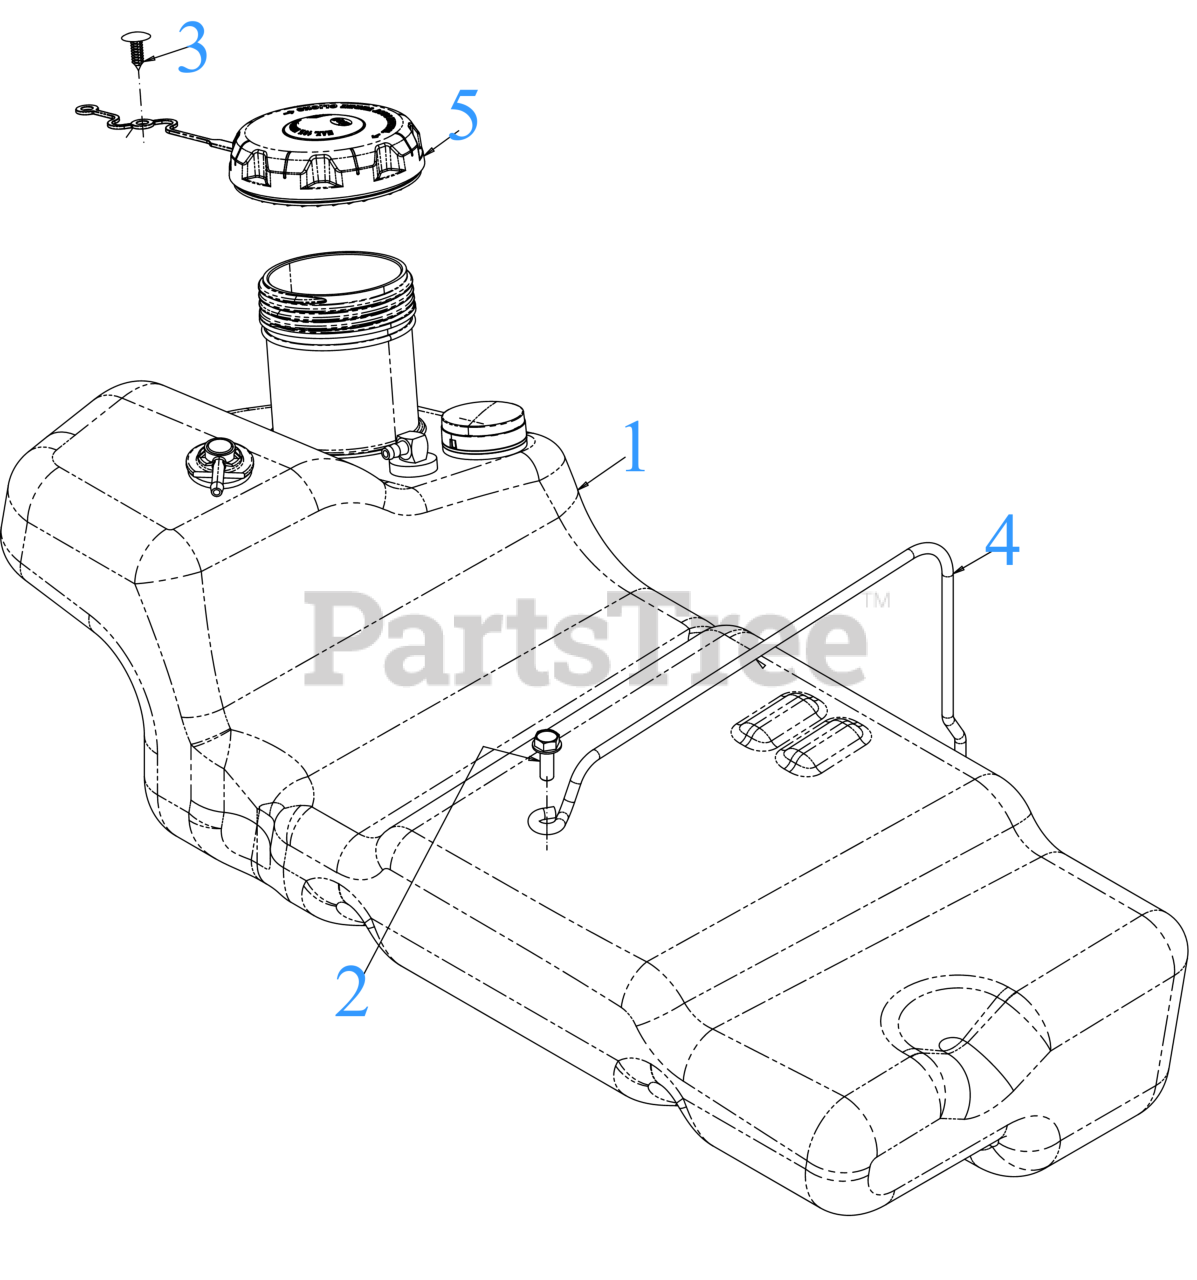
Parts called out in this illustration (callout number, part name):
1	FUEL TANK (5.5 GAL)
2	SCREW 5/16-18 x 1.25
3	RATCHET CLIP .250
4	FUEL TANK RETAINER
5	FUEL CAP (W/TETHER)
